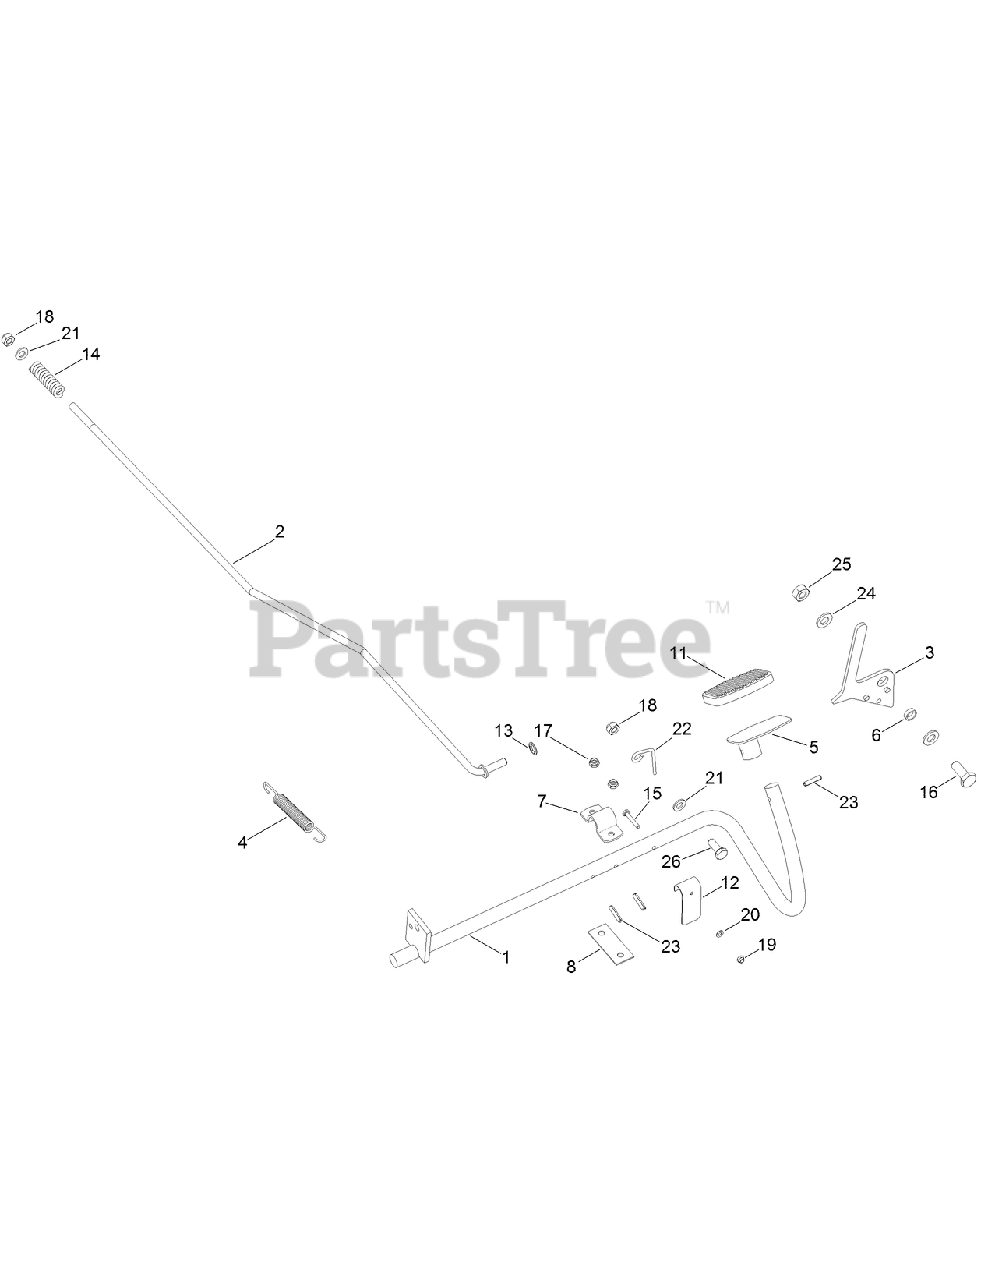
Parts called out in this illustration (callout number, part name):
2	ROD-BRAKE, LINKAGE
3	LEVER-PARKING BRAKE
4	SPRING
5	PEDAL-TRAVEL, BRAKE
6	SPACER
11	PAD-PEDAL
12	BRACKET-PARKING BRAKE
13	WASHER
14	SPRING-BRAKE
15	SCREW-HEX
16	SCREW-HEX
17	NUT-LOCK
18	NUT-LOCK, NI
19	NUT-HEX
20	Washer
21	WASHER-PLAIN
22	SPRING-LEVER
23	PIN-SPRING
24	WASHER-FLAT
25	NUT-LOCK, NI
26	SCREW-HH
